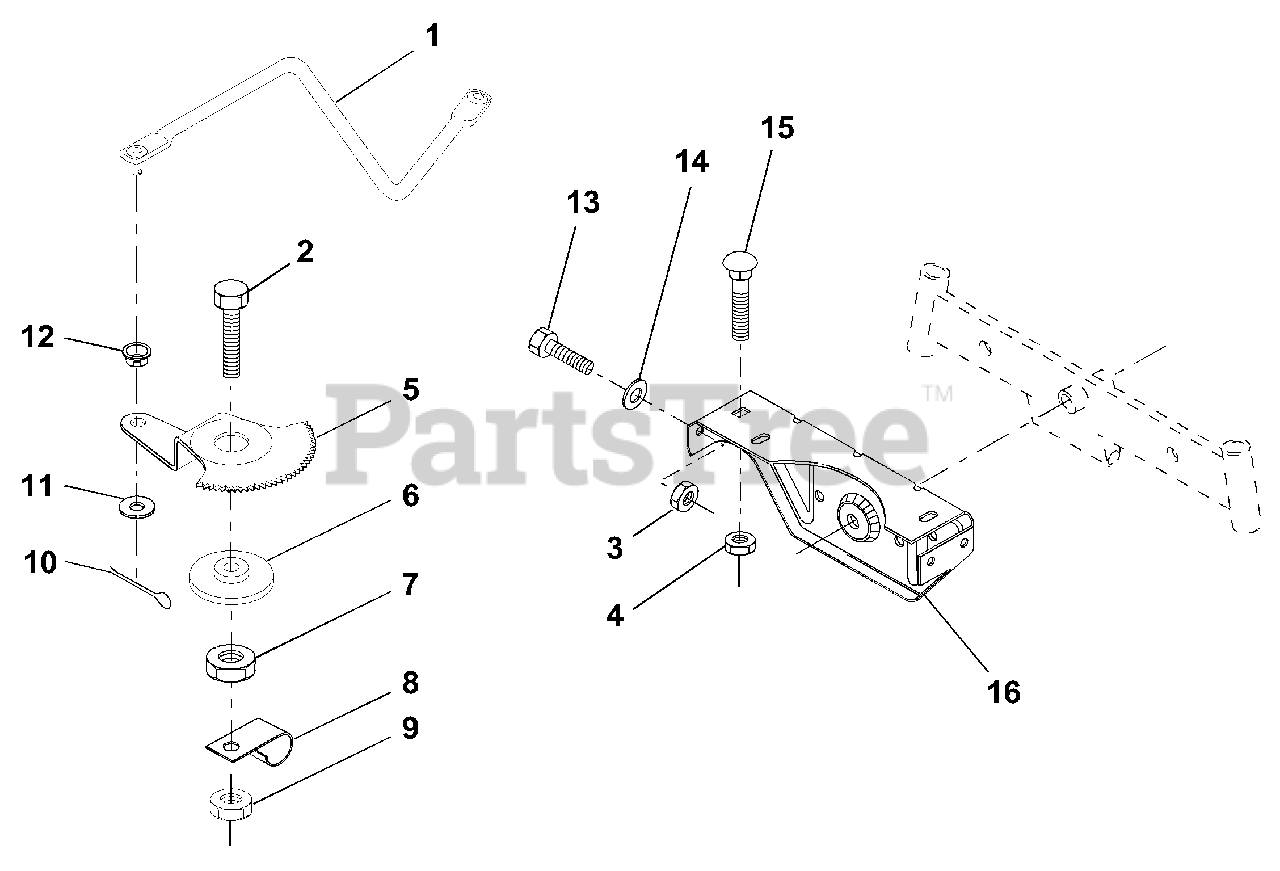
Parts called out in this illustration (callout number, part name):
1	Link, Drag
2	Bolt, Hex, Fin. 1/2-13 x 1-3/4
5	Gear, Sector
7	Nut, Heavy Hex, Top Lock 1/2-13 UNC
8	Clip, Insulated
9	Nut, Crownlock 3/8-16
10	Pin, Cotter 1/8 x 3/4
11	Washer 13/32 x 13/16 x 16 Gauge
13	Bolt, Hex Head 5/16-18 UNC x 1
14	Washer 11/32 x 7/8 x 16 Gauge
15	Bolt, Carriage 3/8-16 UNC x 3/4
16	Support, Front Axle
20	Nut, Crownlock 3/8-16
21	Nut, Crownlock 5/16-18
